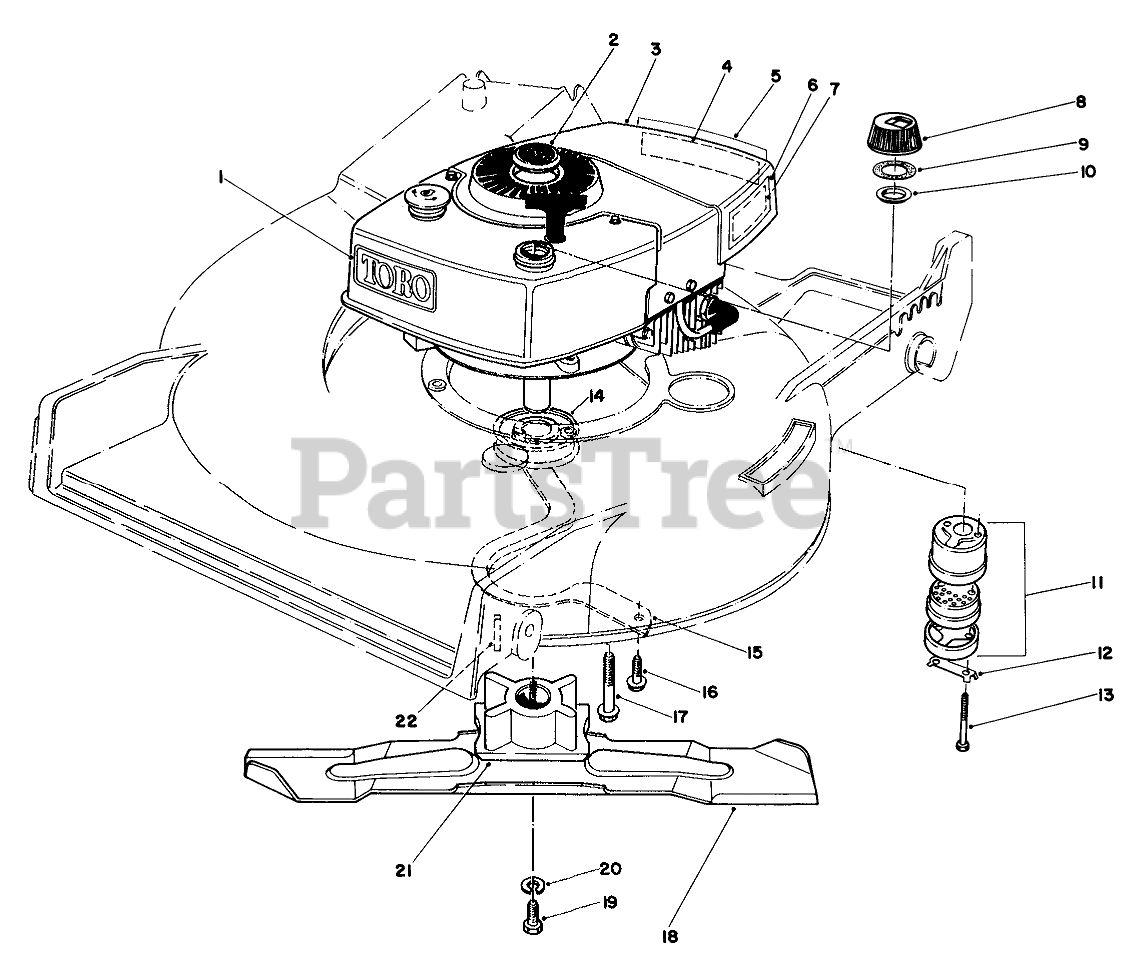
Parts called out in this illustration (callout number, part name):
1	Decal Tow
2	Plug Button
3	Engine
4	Decal Maintenance
5	Decal-Primer Bulb
6	Decal-Maintenance
7	Decal-Maintenance
8	Gas Cap (Incl. Ref. #9 & 10)
9	GASKET
10	GAS CAP BAFFLE
11	Muffler Assembly (Incl. Ref. #12 & 13)
12	CLIP - LOCKING
13	SCREW-HH
14	Pulley
15	BELT GUIDE
16	Screw
17	3/8-16 X 2 CAPSCREW
18	BLADE-21in
19	SCREW-BLADE
20	WASHER-LOCK
21	BLADE RETAINER(DEEP)
22	KEY-SQUARE
